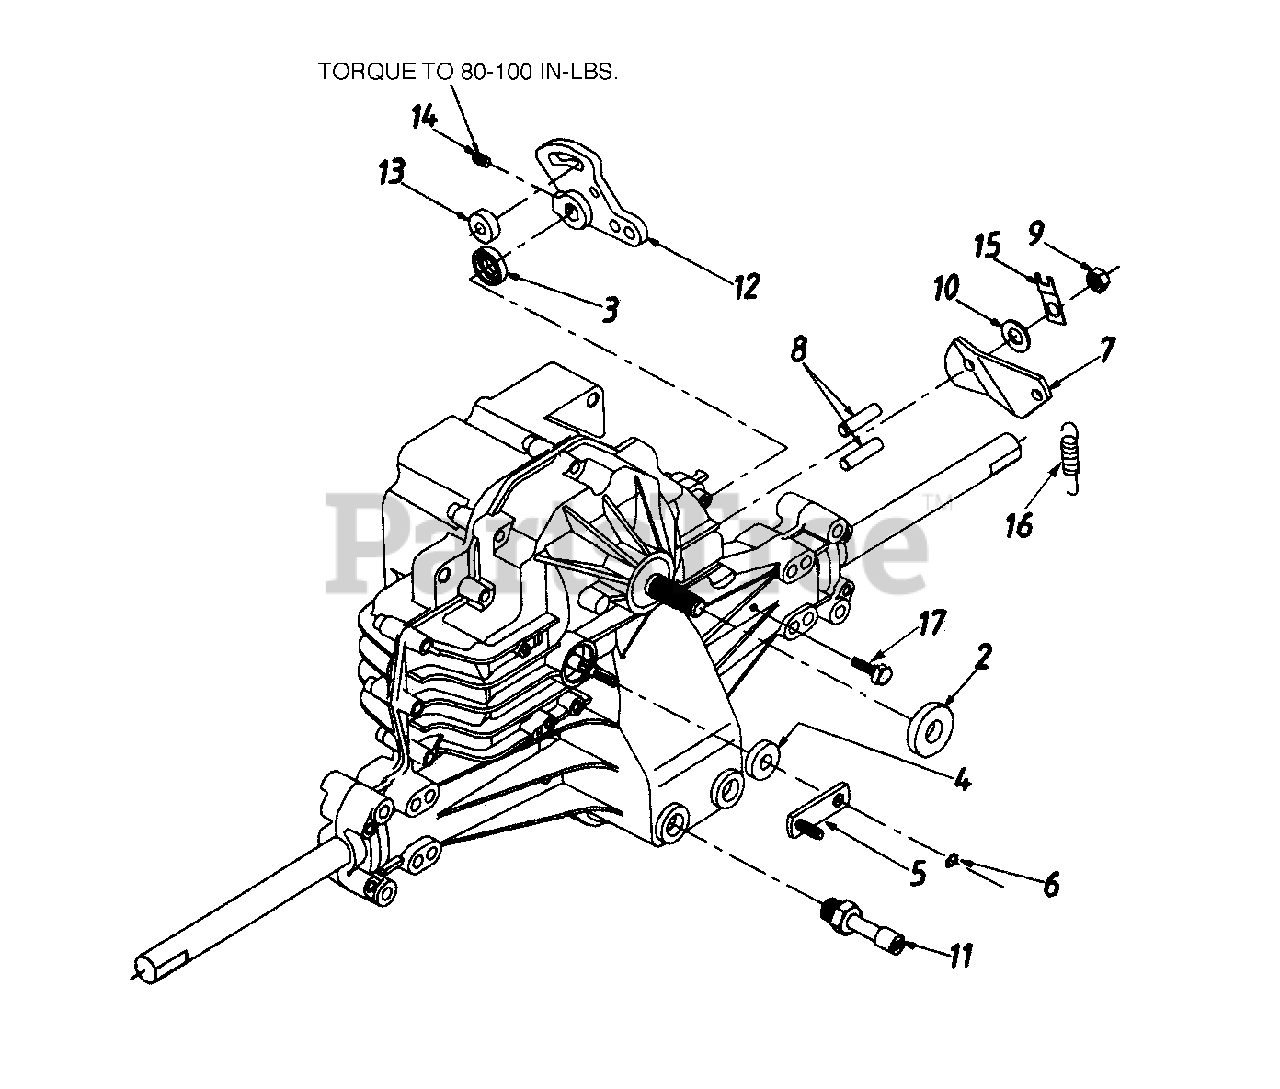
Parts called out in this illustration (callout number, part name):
4	Seal - Lip 10 x 25 x 7
5	Arm - Bypass
6	Ring - Retaining
7	Arm - Actuating
8	Pin - Actuating
9	Nut - Hex Lock 5/16-24 UNJC
10	Washer 7/16" x 7/8" x .060"
11	Breather Ass'y.
12	Arm - Control
13	Puck - Dampener
14	Set Screw
15	Strap, Locking
16	Spring, Extension
17	Self Tapping Screw #10-32 x .5"
